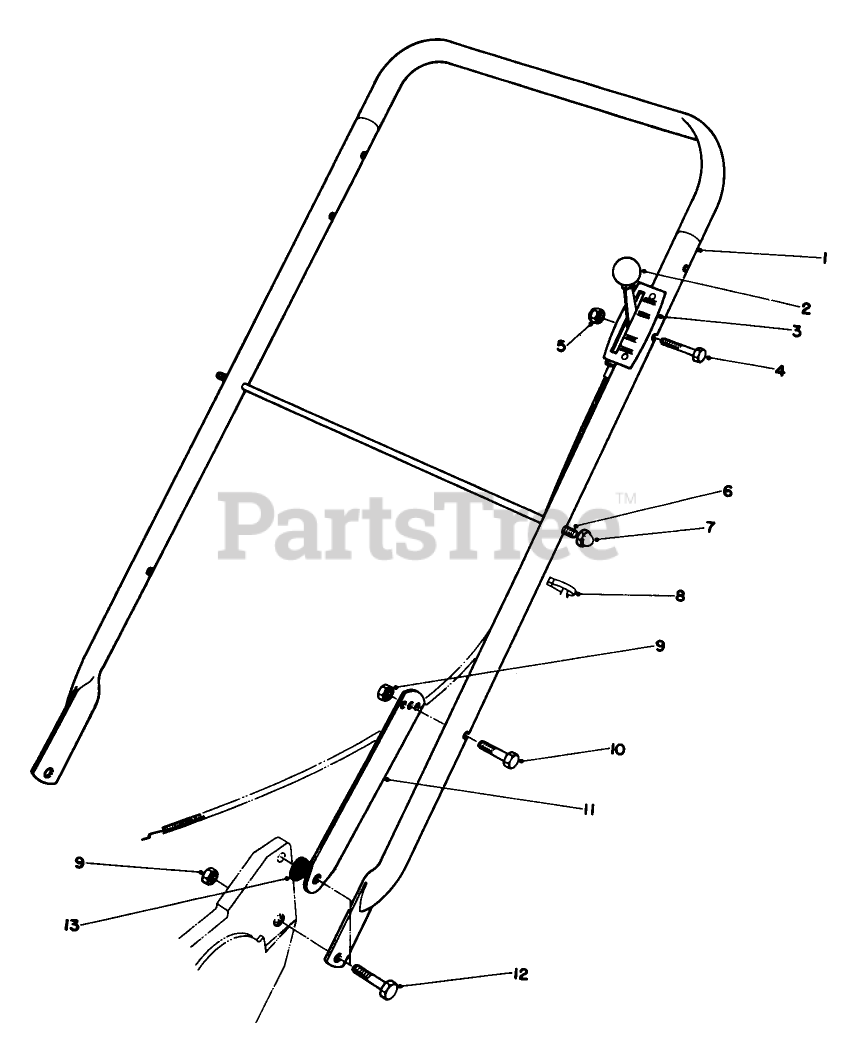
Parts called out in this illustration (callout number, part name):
2	KNOB-CONTROL
4	SCREW-HH
5	NUT-LOCK, NI
6	ROD-SUPPORT, BAG
7	NUT-CAP
9	NUT-LOCK, NI
10	SCREW-HH
12	SCREW-SHOULDER
13	HANDLE LATCH SPACER
